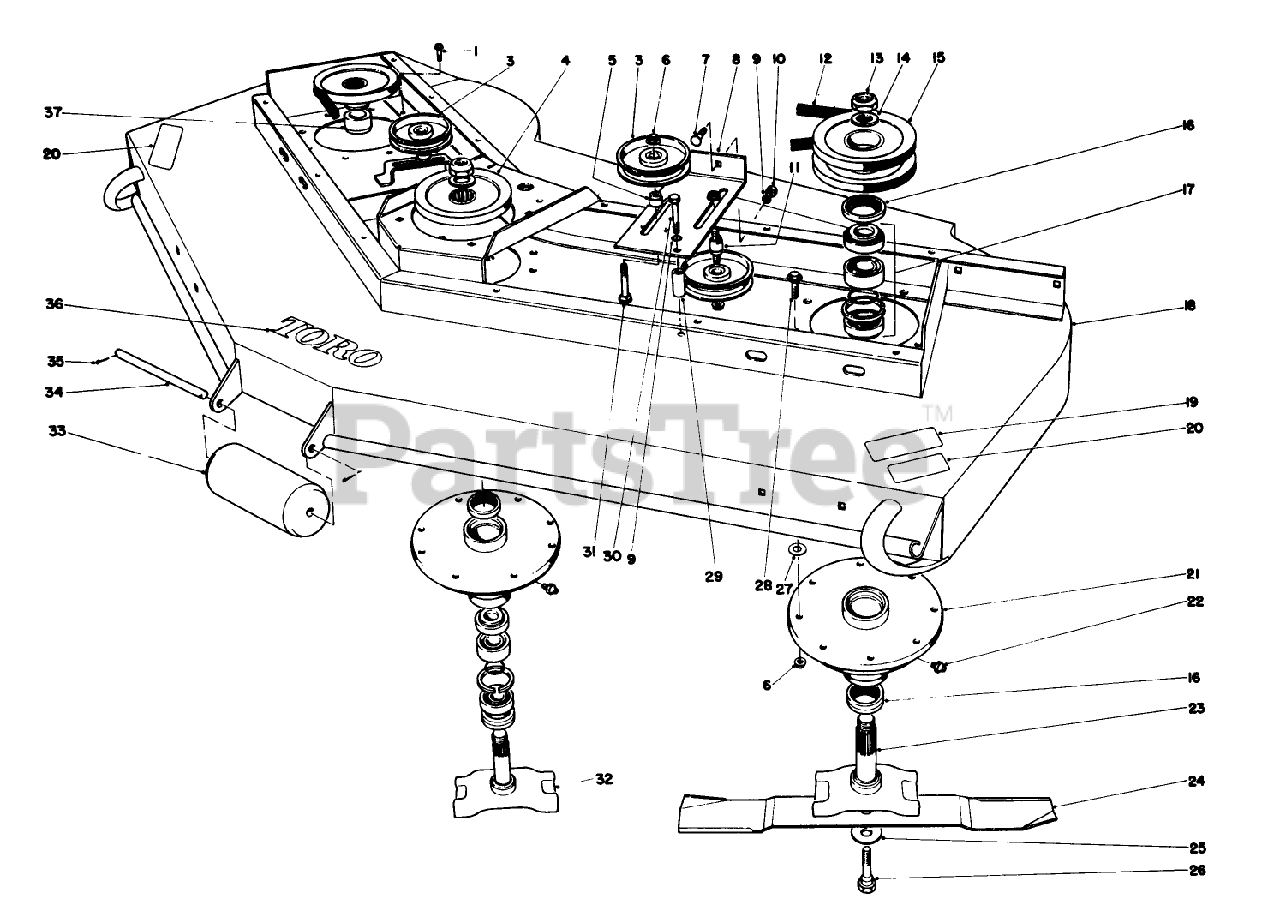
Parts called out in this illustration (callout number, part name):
1	SCREW-HHF
3	PULLEY-IDLER
4	PULLEY AND HUB ASM
5	SPACER-IDLER PULLEY
6	NUT-HF
7	SCREW-CARR
8	Idler Mount L.H.
9	WASHER-LOCK
10	NUT-HEX
11	STUD-IDLER
12	V-BELT
13	NUT-LOCK, NI
14	WASHER-THRUST
15	PULLEY-L.H. W.A.
16	SEAL-OIL
17	BEARING ASM
18	Cutter Deck
19	Decal-Caution
20	DECAL-CAUTION, BLADE
21	Spindle Housing
22	FITTING-GREASE
23	OUTER SPINDLE WA
24	BLADE-STANDARD, LH, 25IN
25	WASHER-BELLEVILLE
26	CAPSCREW
27	WASHER-FLAT
28	SCREW-HHF
29	SPACER-IDLER MOUNT
30	SCREW-HH
31	SCREW-CARR
32	Spindle Ctr.
33	ROLLER-FRONT
34	ROLLER SHAFT
35	PIN-COTTER
36	TORO LOGO DECAL
37	Spacer R.H.Spindle
